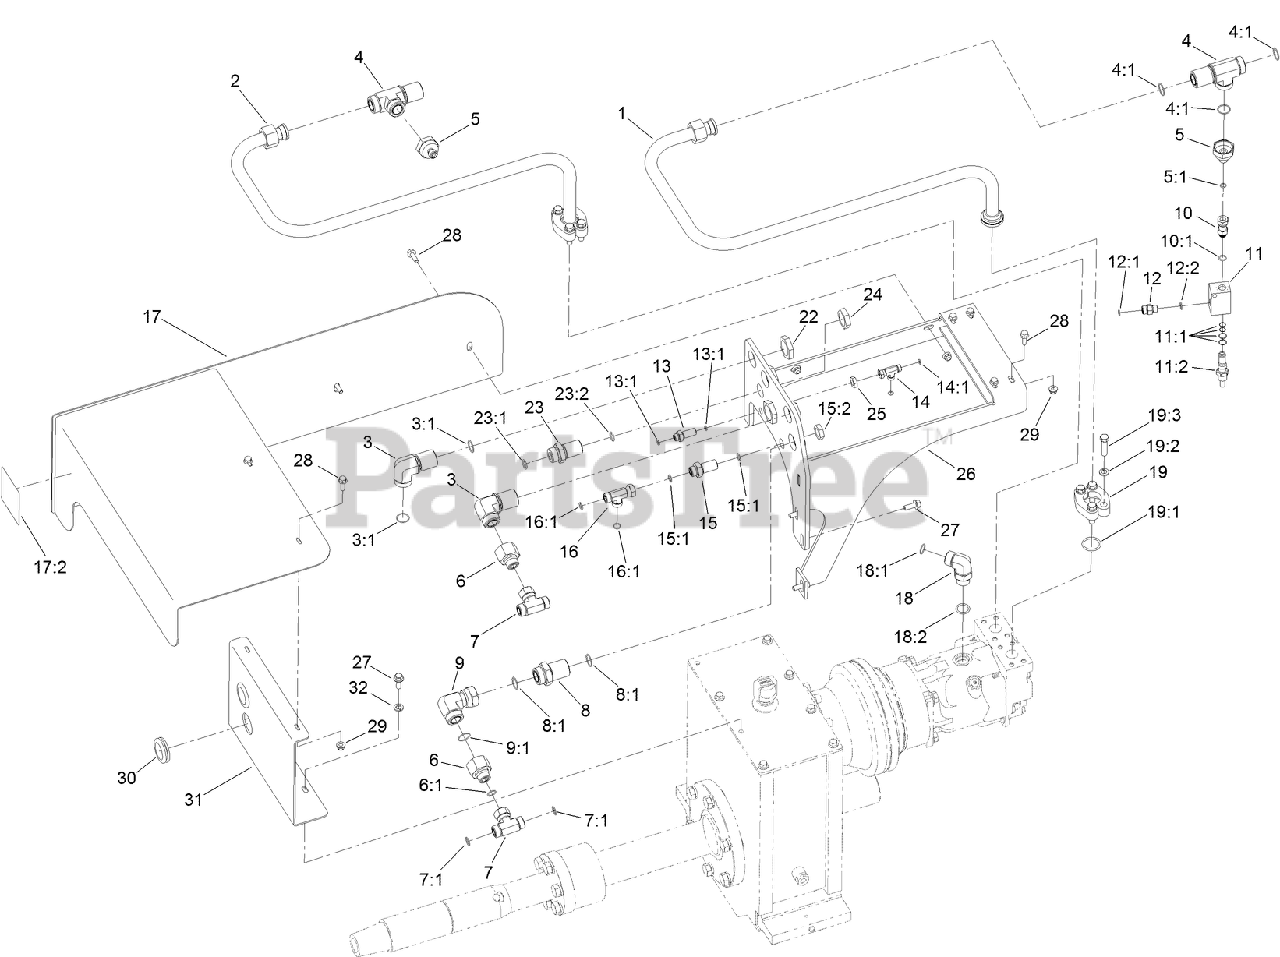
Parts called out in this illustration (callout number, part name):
1	TUBE-HYD, ROTARY B (BULKHEAD TO MOTOR)
2	TUBE-HYD, ROTARY A (BULKHEAD TO MOTOR)
3	FITTING-ELBOW, 90
3:1	O-RING
4	FITTING-TEE, BULKHEAD
4:1	O-RING
5	FITTING-REDUCER
5:1	O-RING
6	FITTING-REDUCER
6:1	O-RING
7	FITTING-HYD, TEE
7:1	O-RING
8	ADAPTER-HYD
8:1	O-RING
9	FITTING-SWIVEL, 90 DEG
9:1	O-RING
10	CONNECTOR-SWIVEL, STRAIGHT
10:1	O-RING
11	VALVE-RELIEF, PRESSURE
11:1	CARTRIDGE-RELIEF
12	FITTING-STRAIGHT
12:1	O-RING
12:2	O-RING
13	UNION-BULKHEAD
13:1	O-RING
14	FITTING-HYD
14:1	O-Ring
15	FITTING-BULKHEAD
15:1	O-RING
15:2	NUT-BULKHEAD
16	FITTING-HYD, TEE
16:1	O-RING
17	CARRIAGE GUARD ASM
17:2	DECAL-WARNING, CRUSHING
18	FITTING-ELBOW-90
18:1	O-RING
18:2	O-RING
19	HYD FLANGE KIT
19:1	O-RING
19:2	WASHER-LOCK
19:3	SCREW-HH
22	NUT-BULKHEAD
23	FITTING-STRAIGHT
23:1	O-RING
23:2	O-RING
24	NUT-BULKHEAD
25	NUT-LOCK
26	MOUNT-HOSE CARRIER, ROTARY
27	SCREW-HHF
28	SCREW-HHF
29	NUT-LOCK, HHF
30	Grommet
31	PLATE-SUPPORT, GUARD
32	WASHER-LOCK
